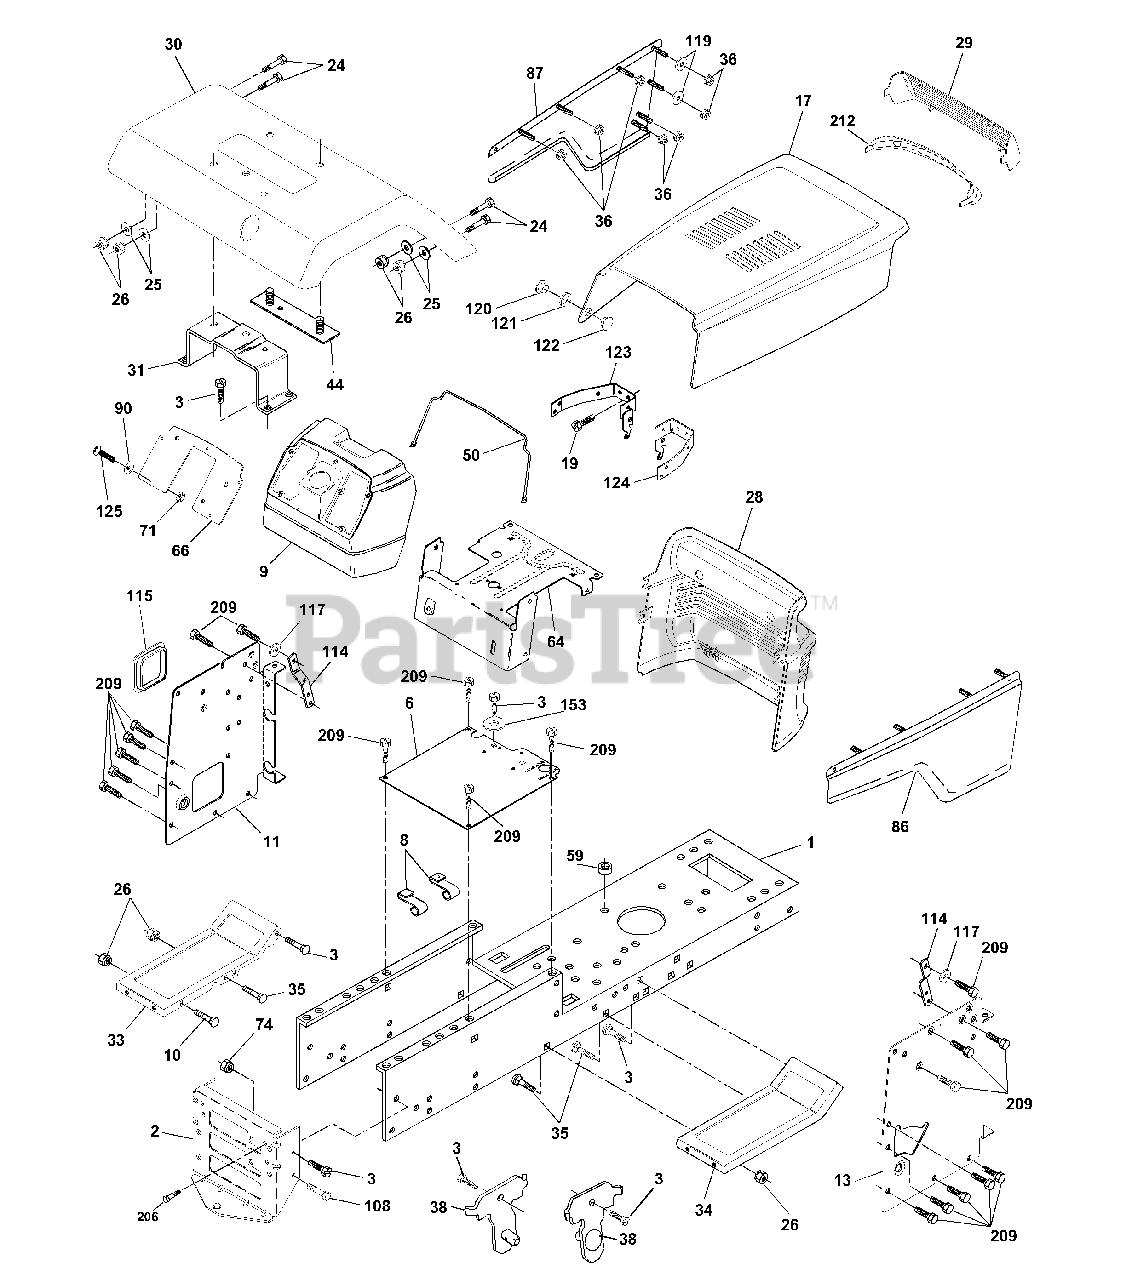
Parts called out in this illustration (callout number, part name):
1	Chassis Wldmt.
2	Drawbar Stretch 94
3	Screw 3/8-16 x 3/4
6	Saddle Flat Lt
8	Clip Insulator
10	Bolt Rd Hd Sqnk. 3/8-16 Unc x 1
11	Panel Dash Lh
13	Panel Dash Rh
19	Screw Hwhd Hi-Lo #13-16 x 3/4
24	Bolt Fin Hex 3/8-16 Unc x 1 Gr. 5
25	Washer 13/32 x 13/16 x 12 Ga.
26	Nut Lock Hex w/Insert 3/8-16 UNC
28	Grill / Lens Asm
29	Lens Grille
30	Fender Asm YTGT
31	Bracket Fender
33	Footrest Pnt. Lh
34	Footrest Pnt. Rh
35	Bolt Rd Hd Sht. Sqnk. 3/8-16 x 3/4
36	Nut Pal
37	Screw Thdrol 5/16-18 x 1/2 Tyt
38	Bracket Asm Pivot Mower Rear
44	Strap Asm Fender
50	Rod Support Hood
59	Bushing Snap Split
64	Dash Lower
66	Plate Dash Slkscr.
71	Nut Keps Hex 1/4-20 Unc
74	Nut Crownlock 3/8-16 Unc
86	Panel Asm. Pnt. Side Rh
87	Panel Asm. Pnt. Side Lh
90	Washer 9/32 x 3/4 x 16 Ga.
108	Bolt Fin Hex 3/8-16 Unc x 3/4
114	Bracket Support Dash
115	Cover Access
117	Washer Serrated Disc 13/32 x 1
119	Washer 9/32 x 1-1/4 x 16 Ga.
120	Rivet Ratchet Female
121	Washer Nylon
122	Rivet Ratchet Male
123	Bracket Asm. Pivot Hood Lh
124	Bracket Asm. Pivot Hood Rh
125	Screw Mach Cr. 1/4-20 x 3/4
153	Washer 13/32 x 1-3/8 x 3 Ga.
206	Bolt Shoulder 5/16-18
209	Screw Hex wsh Thdrol 3/8-16 x 3/4
212	Insert Lens Reflector
